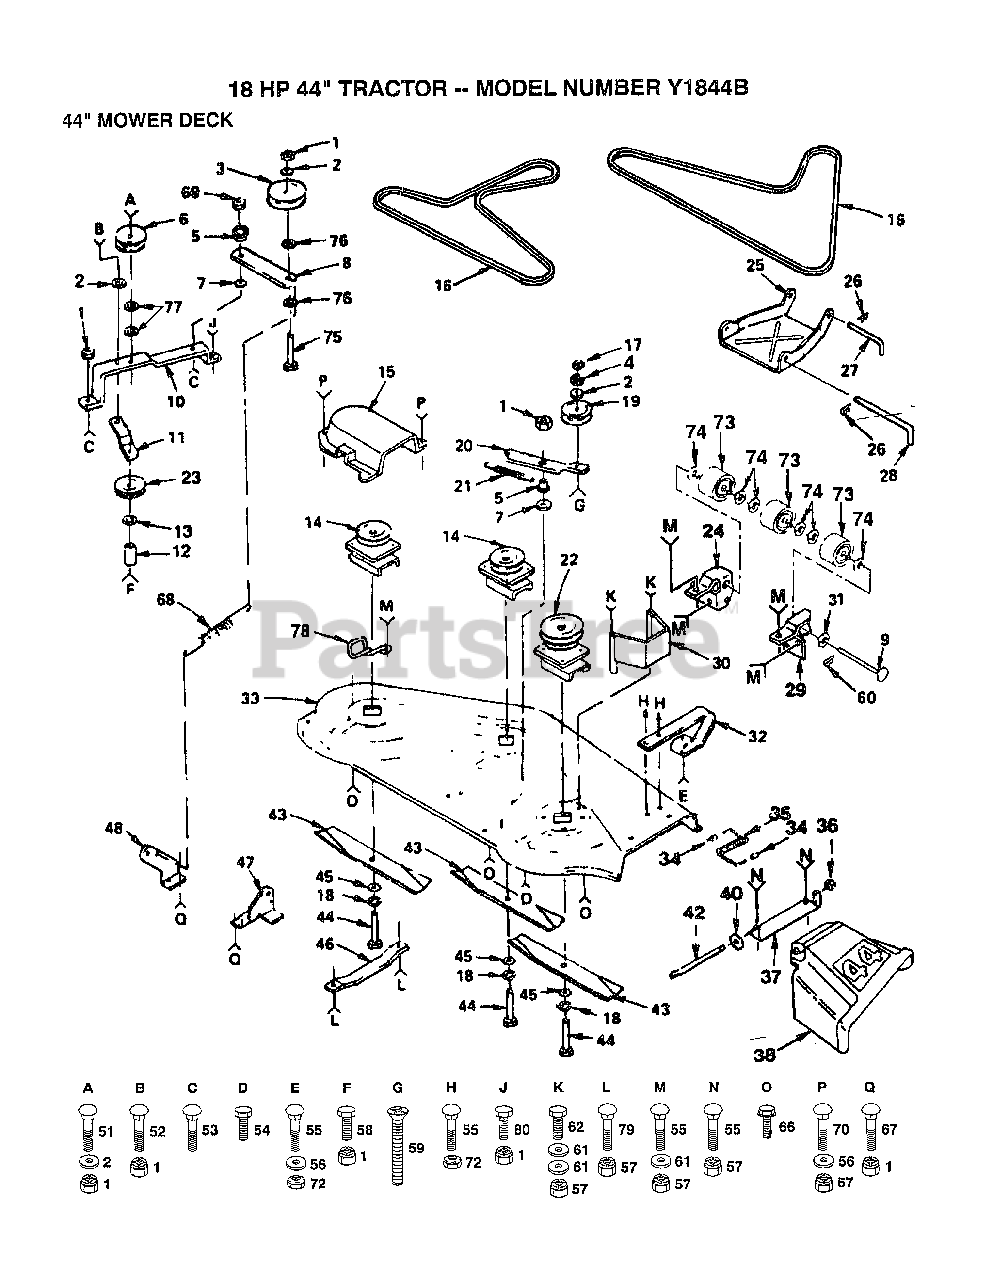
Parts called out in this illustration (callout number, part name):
2	WASHER
3	PULLEY IDLER
4	LOCKWASHER
5	SPACER RETAINER
6	IDLER-INSIDE T
7	"WASHER, WEAR LT"
8	ARM IDLER
9	PIVOT PIN T
10	"SUPPORT YT, BAR"
11	BRACE-IDLER YT
12	SPACER
13	WASHER
15	GUARD YT
16	BELT-V.79.1.MWR
17	NUT.HEX.3/8-16UNC
19	IDLER.FLAT.GTV
20	ARM-IDLER YT
22	JACKSHAFT
23	IDLER-FLAT T
24	BRACKET LH YTH
25	LINK.PARALLEL
26	SPRING.RETAINER
27	"ROD, FRT. PARAL T"
28	HINGE PIN T
29	BRACKET RH YTH
30	GUARD BELT HYT
34	CAP-SLEEVE LT
36	NUT PUSH M
38	DEFLECTOR SHIELD
40	WASHER
42	ROD-HINGE T
44	BOLT.3/8-24X1-1/2
45	WASHER
46	RUNNER-LH M
47	BRKT SUSP REAR RH
48	BRKT SUSP REAR LH
51	BOLT
53	BOLT
55	BOLT
56	WASHER
58	BOLT - HEX 3/8 - 16 X 3
59	SCREW YT
60	COTTER PIN
61	WASHER M
62	BOLT
66	SCREW
67	BOLT
68	"SPRING.EXT.8.5"""
69	LOCKNUT
73	ROLLER T
74	WASHER T
75	BOLT
76	WASHER
77	WASHER
78	BELT RETIANER
79	BOLT
80	BOLT
